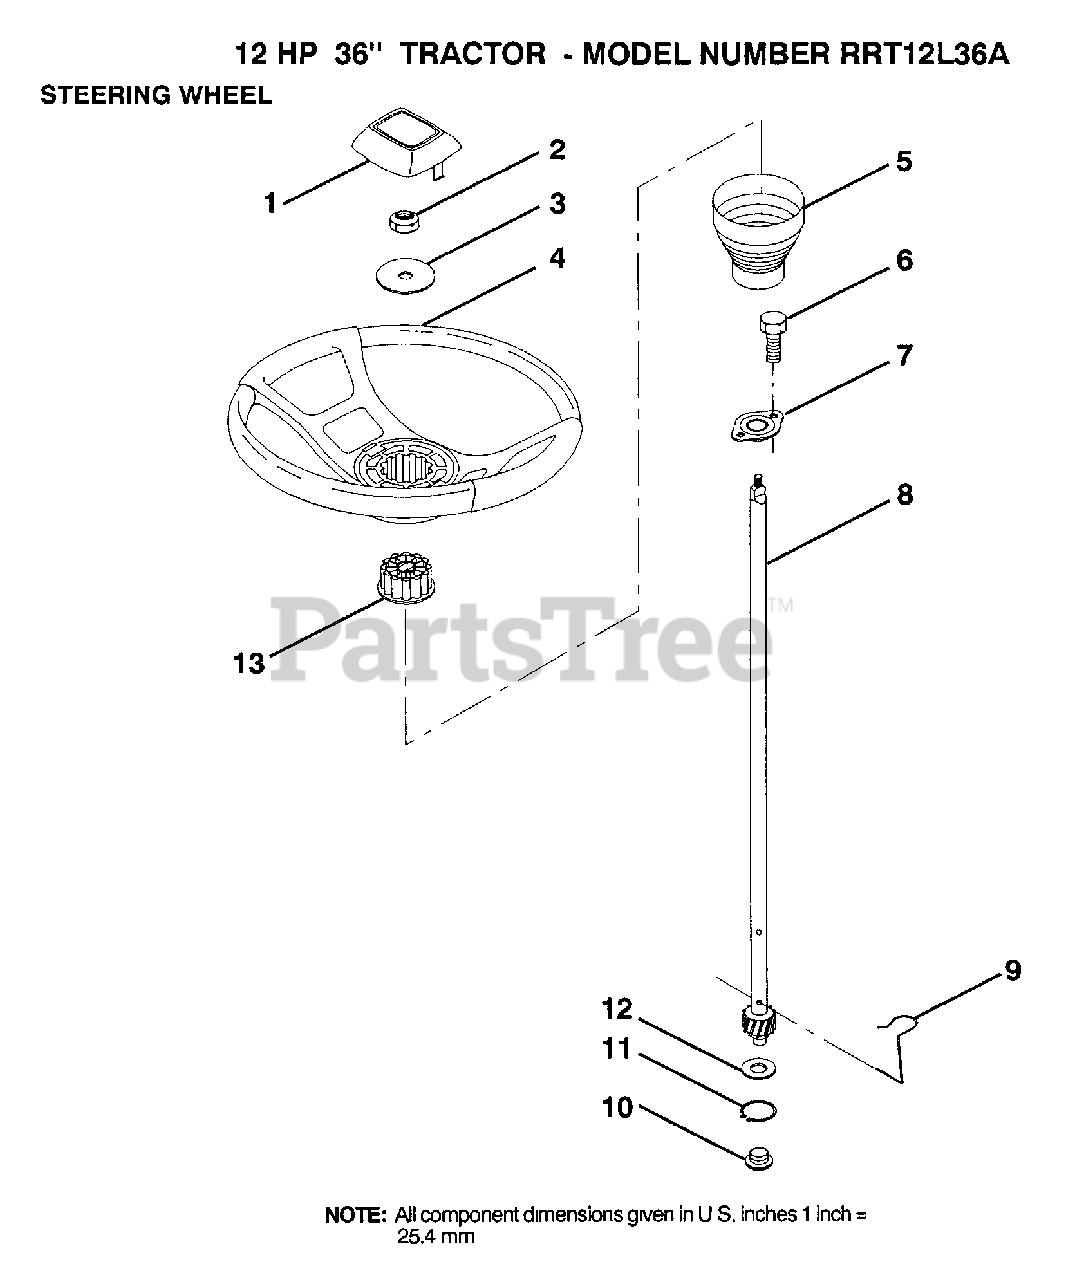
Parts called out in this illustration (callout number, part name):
1	ST WHL INSERT CAP
2	GRIPCO NUT
3	WASHER T
5	SLEEVE STEERING
9	STEERING CLIP
10	BUSHING STEER LWR
11	RING
12	WASHER LT
13	ADAPTER-WHEEL LT
